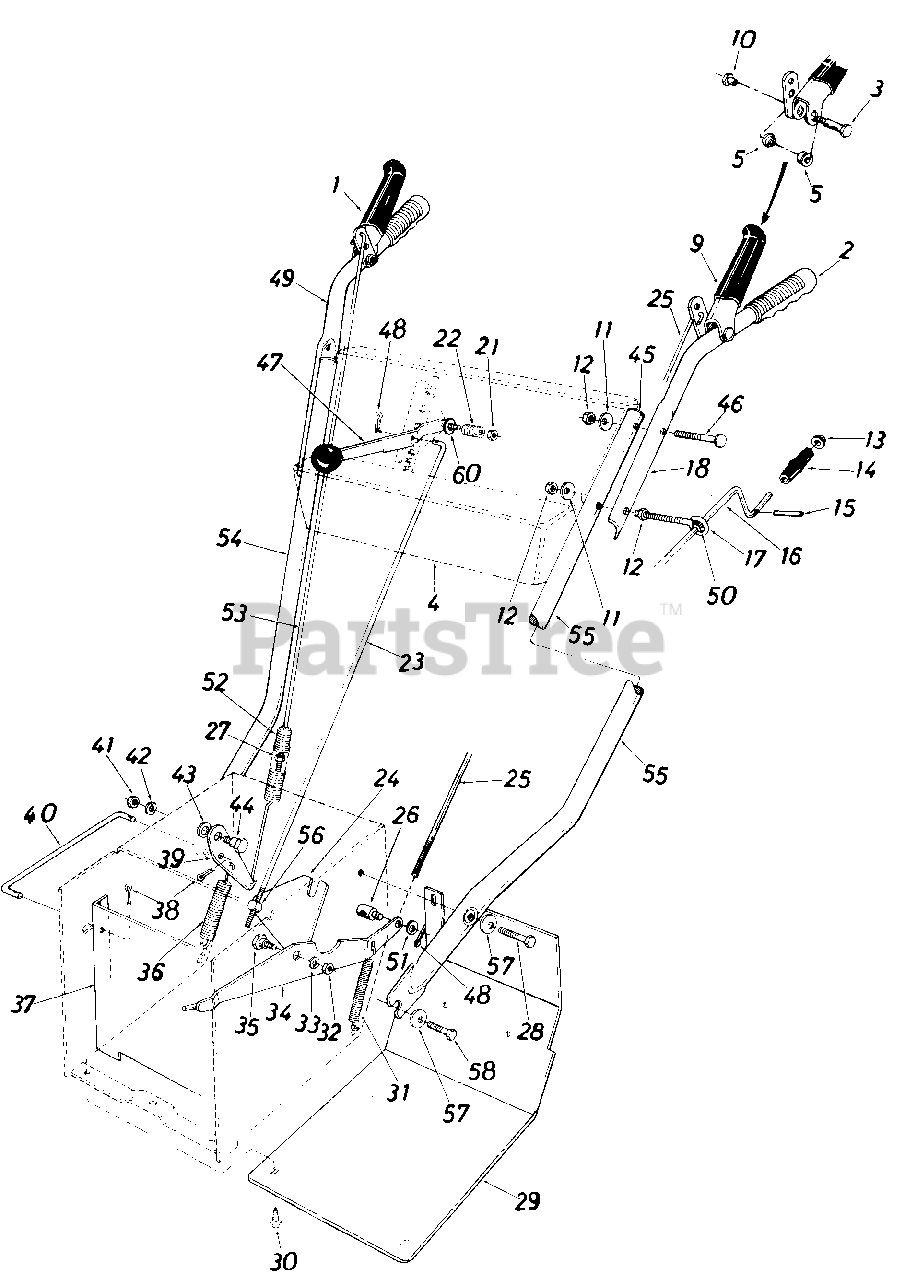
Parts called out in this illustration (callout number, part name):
1	Clutch Grip Ass'y.-R.H.
2	Grip
3	Shoulder Bolt .374 Dia. x 1.53" Lg.
4	Handle Panel Ass'y.
5	Hex Flange Plastic Bearing .380" 1.D.
9	Clutch Grip Ass'y.-L.H.
10	Shoulder Nut 1/4-20 Thd.
11	Bell-Wash 34" I.D. x .88" O D
12	Hex Nut 5/16-18 Thd.
13	Push Nut 3/8" Rod
14	Knob 3/8" Rod
15	Roll Pin .12 Dia. x .63" Lg.
16	Chute Crank Ass'y. 39" Lg
17	Eye Bolt 5/16-18 x 5.0" Lg.
18	Upper Handle-L.H.
21	Hex Ins. Jam L-Nut 3/8-24 Thd .
22	Compression Spring .50" O.D. x .88" Lg.
23	Shifting Rod 5/16" x 32.50'
24	Shifting Linkage Bracket
25	Lockout Rod .214" Dia. x 36.0" Lg.
26	Adjustment Ferrule 1/4-20
27	Hex Ins. L-Nut 1/4-20 Thd.
28	Hex Bolt 3/8-16 x 2.00" Lg.*
29	Frame Cover
30	Hex Wash. Self-Tap Scr. 1/4-20 x .50" Lg.
31	Extension Spring .38" O.D. x 3.25" Lg.
32	Hex Jam Nut 3/8-16 Thd.
33	IL-Wash. 3/8" I.D.
34	Auger Clutch Bracket Ass'y.
35	Shld. Bolt .625" Dia. x .170
36	Extension Spring .75" O.D. x 4.31 " Lg.
37	Drive Pulley Support Brkt. Ass'y.
38	Cotter Pin 3/32" Dia. x .75" Lg.
39	Drive Clutch Bracket
40	Drive Clutch Rod
41	Hex Jam Nut 3/8-16 Thd.
42	L-Wash. 3/8" I.D.
43	Fl-Wash. .34" I.D. x .75" O.D.
44	Shld. Bolt .625" Dia. x .170
45	Plastic Plug
46	Carriage Bolt 5/16-18 x 2.0" Lg.
47	Shift Handle Ass'y.
48	Int. Cotter Pin 5/16" Dia.
49	Upper Handle-R.H.
50	Plastic Bushing
51	Fl-Wash. .28" I.D. x .62" O.D.
52	Extension Spring .75" O.D. x 5.00" Lg.
53	Lockout Rod .214" Dia. x 32" Lg.
54	Lower Handle-R.H.
55	Lower Handle-L.H.
56	Adjustment Ferrule
57	Bell-Wash. .40" I.D. x .88" O.D.
58	Hex Wash. Self-Tap Scr. 3/8-16 x .75" Lg.
60	Bell-Wash. .40" I.D. x .88" O.D.
